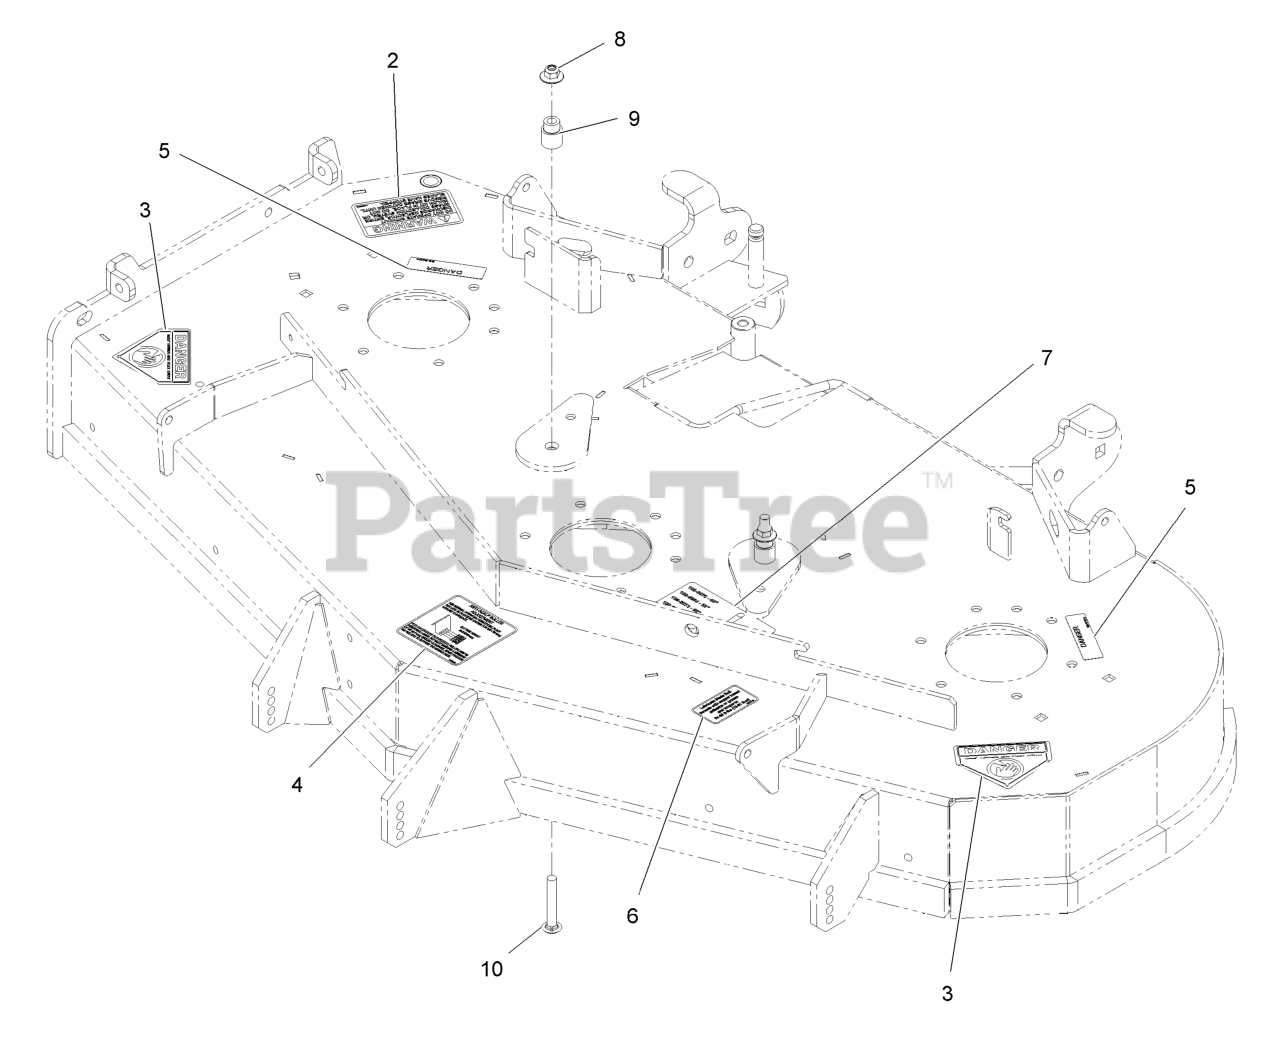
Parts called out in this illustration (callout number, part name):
2	DECAL-WARNING, DISCHARGE
3	DECAL-DANGER
4	DECAL,ANTISCALP
5	DECAL-COVER, MISSING
6	DECAL,BOLT TORQUE
7	DECAL,BELT ROUTING
8	Nut-Nyloc 3/8-16 Flg
9	BUSHING-IDLER
10	SCREW-CARR
